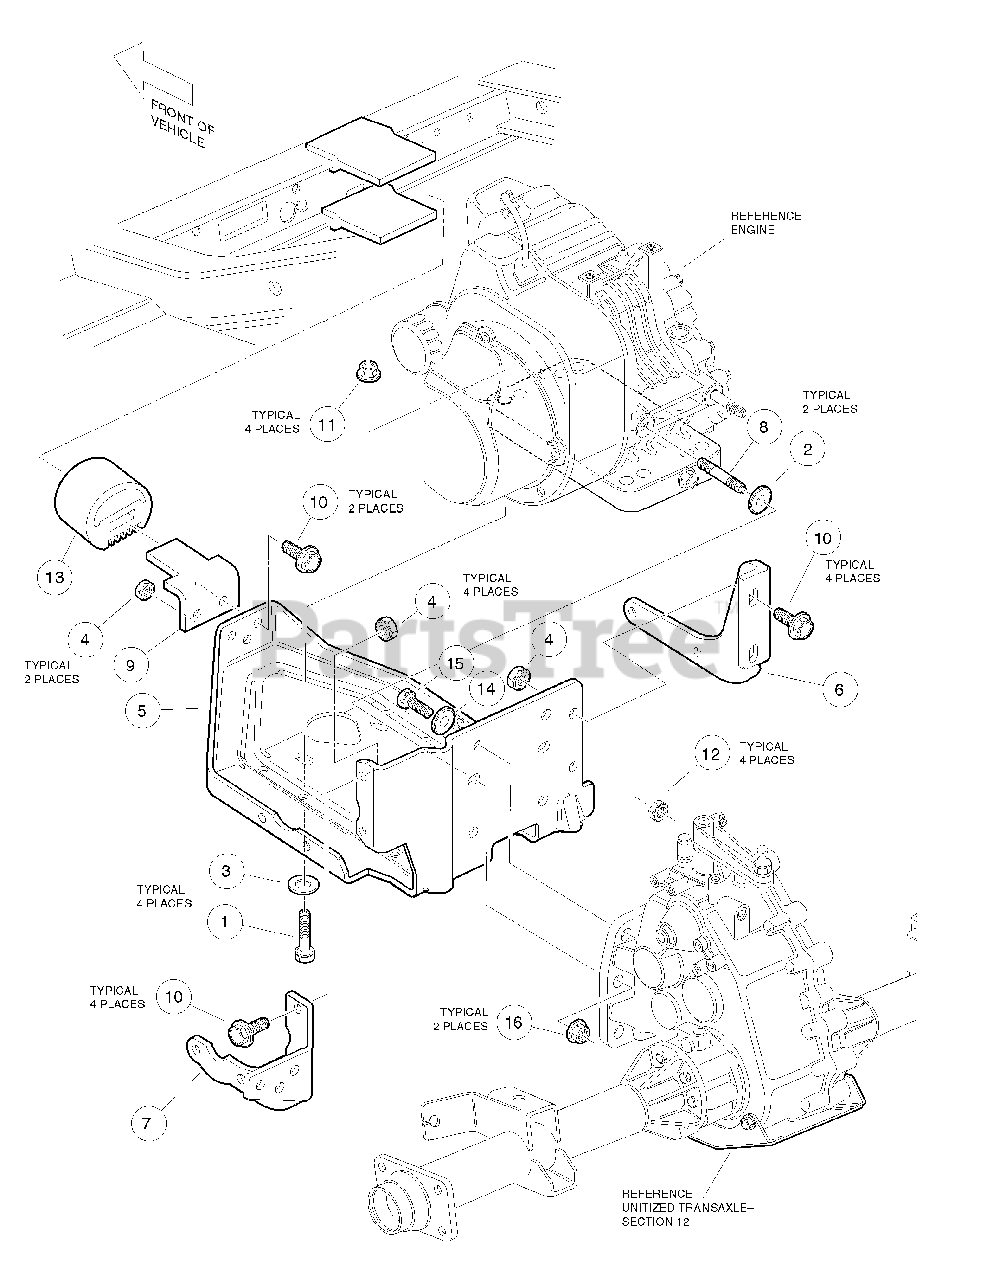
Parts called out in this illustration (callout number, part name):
1	Bolt, Hex-Head, 5/16-18 X 1.50
2	Washer, 5/16 Flat
3	Washer, 5/16 Extra Thick Flat
4	Nut, 5/16-24 Hex Head Cone
5	Plate, Engine Mounting
6	Stiffener
7	Stiffener
8	Stud, M8-1.25 X 50 mm Two-Ended
9	Snubber Bracket
10	Screw, 5/16-24 X 0.875 Grade-8
11	Locknut, 5/16-18 Hex Flange
12	Locknut, 3/8-16 Flanged Dimple
13	Inner Frame Snubber
14	Washer, 3/8 Type A Flat
15	Screw, Cap-hex Hd 3/8-16x1.25
16	Nut Flg, M8 X 1.25 Serrated
